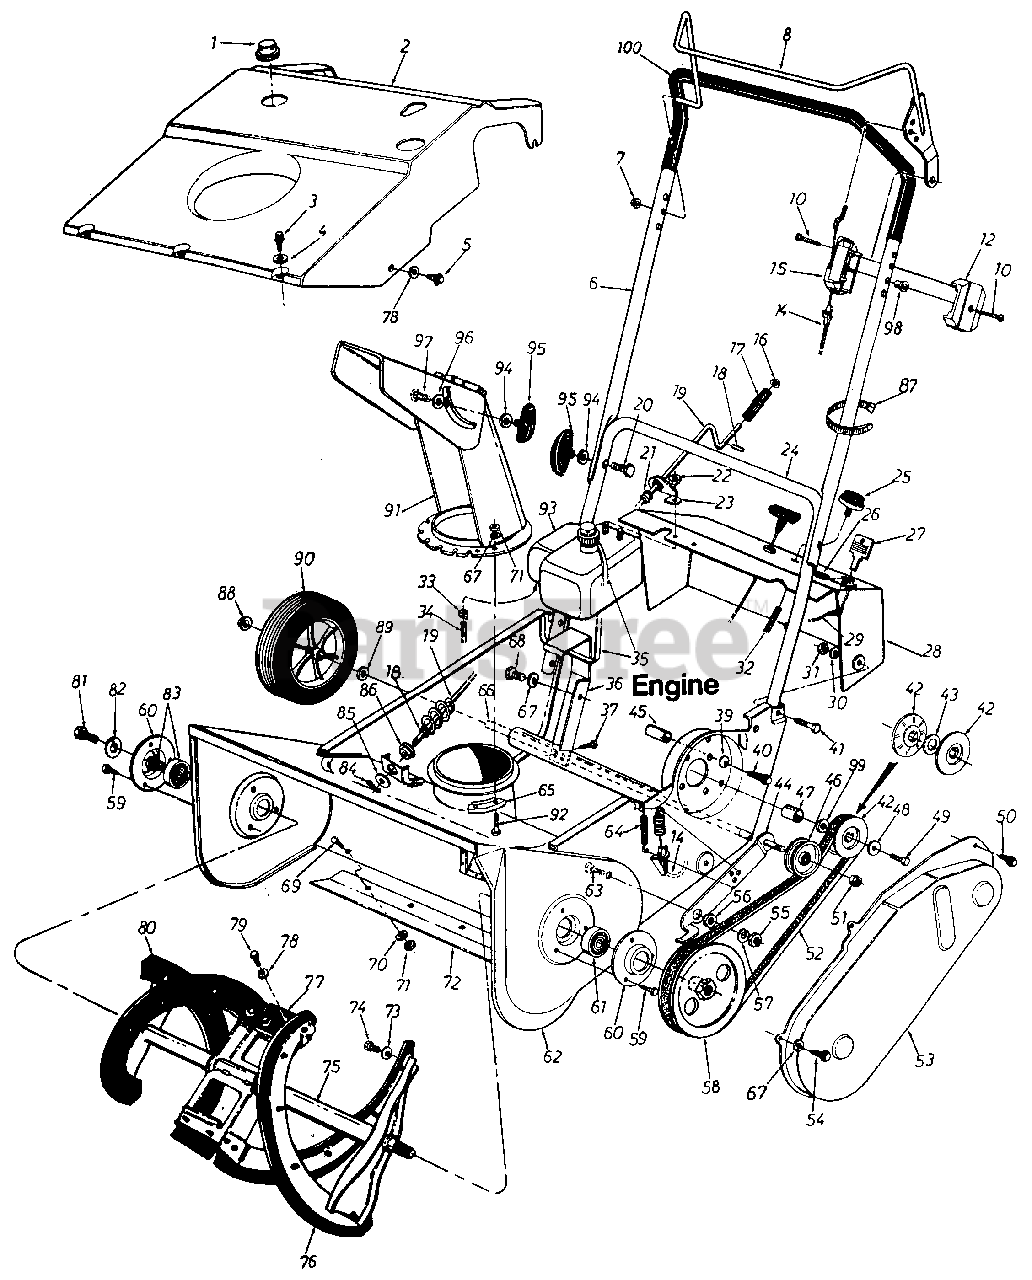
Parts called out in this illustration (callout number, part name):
1	CAP-GAS
2	SHROUD-21IN
3	SCREW-HEX B-TAP #10 X .38
4	WASHER-SPRING
5	SCREW-HEX L-WASH HD
6	HANDLE-UPPER
7	NUT-SPEED
8	HANDLE ASSY-CONTROL-LH
10	SCREW-TRUSS MACH
12	PANEL HALF-CONTROL
14	CABLE-CLUTCH
15	PANEL HALF-CONTROL
17	KNOB-CHUTE CRANK
18	PIN-ROLL 1/18 DIA
19	CRANK ASSY-CHUTE
20	BOLT-CARRIAGE 5/16-18 X 1.75
21	GROMMET
22	NUT-HEX CENTER L-1/4-20
23	BRACKET-CHUTE CRANK
24	HANDLE-LOWER
25	PRIMER
27	KEY-STARTER-TEC
28	PANEL-DASH
29	WIRE-IGNITION
30	WASHER-LOCK-5/16
31	NUT-HEX 5/16-18
32	HOSE-PRIMER
33	CLAMP-HOSE
34	FUEL LINE-15IN
35	TIE-CABLE
36	BRACKET-ENGINE SUP
37	SCREW-HEX L-WASH HD
39	WASHER-BELL .337 X .867 X .057
40	SCREW-HEX 5/16-18 X 1.50
41	SCREW-HEX 5/16-18 X 1.50
42	PULLEY-HALF-V
43	WASHER-FL-.635 ID X .93 OD X .060
44	BRACKET ASSY-IDLER
45	SPACER
46	PULLEY-IDLER
47	SPACER
48	WASHER-BELL .337 X .867 X .057
49	SCREW-HEX 5/16-24 X .75
50	SCREW-HEX L-WASH HD
51	NUT-HEX LOCK 3/8-24
52	BELT-V
54	SCREW-HEX B-TAP 1/4 X .38
55	NUT-HEX 5/16-18
56	SPACER-SHLD
57	WASHER-LOCK-5/16
59	SCREW-HEX B-TAP 1/4 X .38
62	HOUSING ASSY-BLOWER
63	SCREW-TRUSS MACH 5/16-18 X .75
64	SPRING-EXTENSION
65	KEEPER-CHUTE FLANGE
66	AXLE-WHEEL
67	LOCK WASHER 1/4 DIA
68	SCREW-HEX WASH SF TAPP
69	BOLT-CARRIAGE 1/4-20 X .62
70	WASHER-FL-.28 ID X .74 OD X .063
71	NUT-HEX 1/4-20
72	PLATE-SHAVE
73	WASHER-FL-.281 ID X .50 OD X .063
74	SCREW-HEX B-TAP 1/4-.62
75	AUGER ASSY 21IN
76	SPIRAL-RUBBER-LH
77	PADDLE-RUBBER
78	WASHER-FL .192 X .625 X .057
79	STUD-1/4-20 X 5/8
80	SPIRAL-RUBBER-RH
81	SCREW-HEX WASH 1/4-20X.75
82	LOCK WASHER 1/4 DIA
83	KIT-BRG & COLLAR
84	PIN-COTTER-3/32 DIA X .75
85	WASHER-FL-.390 ID X 1.50 OD X .075
86	BUSHING-HEX
87	CLAMP-CABLE 7/8
89	WASHER-FL-.510 ID X .75 OD X .033
90	WHEEL ASSY W/TIRE-6 X 1.5
91	CHUTE ASSY
92	BOLT-CARRIAGE 1/20 X .75
93	TANK-FUEL
94	WASHER-BELL .337 X .867 X .057
95	KNOB-HANDLE ASSY
96	WASHER-FL
97	BOLT-CARRIAGE 5/16-18 X .62
98	PIN-CONTROL DISC
